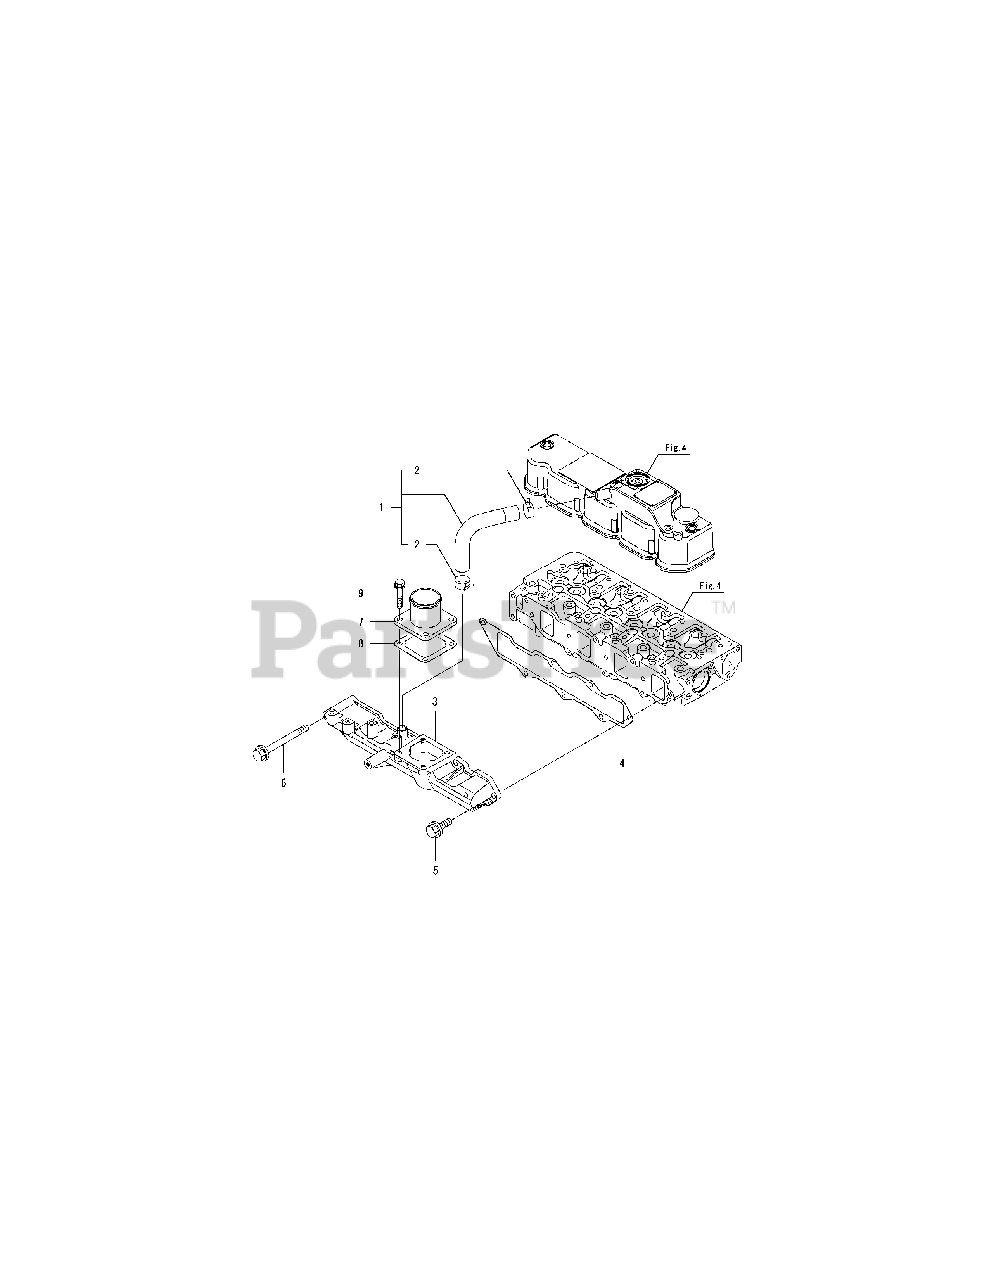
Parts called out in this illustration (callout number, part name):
1	PIPE, BREATHER
3	MANIFOLD, AIR INTAKE
4	GASKET, MANIFOLD
5	BOLT M 8X 20 PLATED
6	BOLT M 8X 80 PLATED
7	JOINT, MANIFOLD
8	GASKET, AIR HEATER
9	BOLT M 8X 20 PLATED
